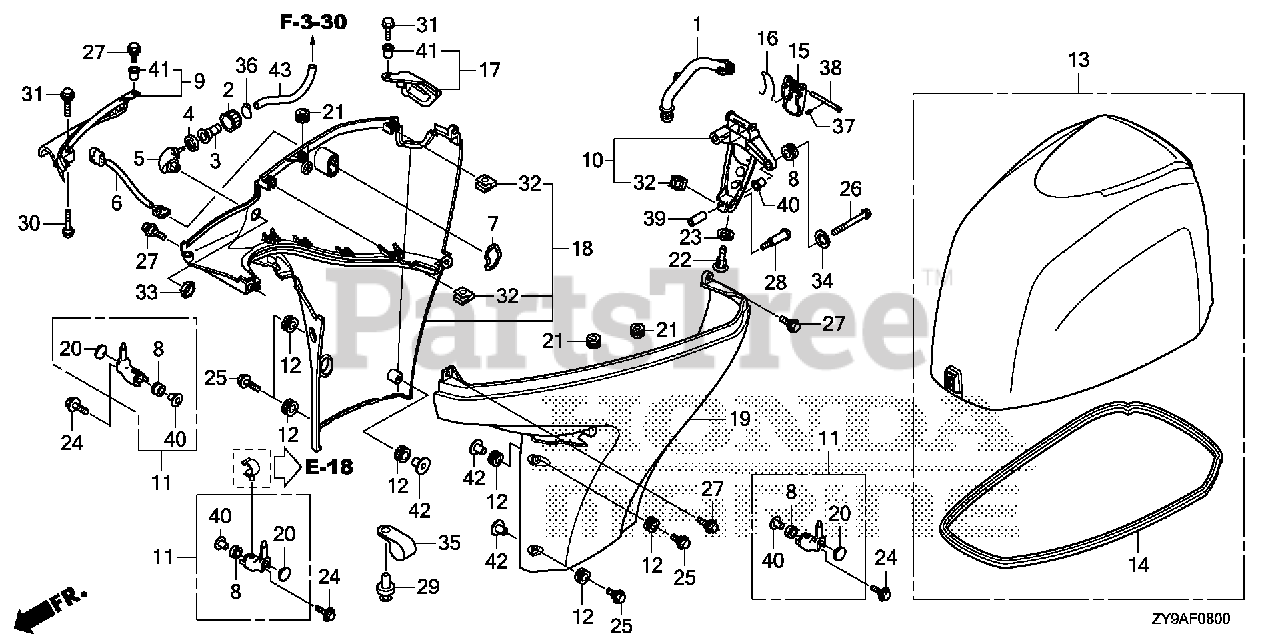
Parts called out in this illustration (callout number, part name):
1	PORT, IDLE EX.
2	NUT, WATER MOUTH
3	JOINT, WATER HOSE
4	SEAT, WATER MOUTH
5	CAP, WATER JOINT
6	SWITCH ASSY., POWER TILT
7	STAY, POWER TILT SWITCH
8	GROMMET, CASE (LOWER)
9	COVER, FR. SEPARATE *NHB14M* (AQUA MARINE SILVER METALLIC)
10	BRACKET, COVER (LOWER)
11	STOPPER ASSY., ENGINE SIDE
12	RUBBER, FENDER MOUNTING
13	COVER ASSY., ENGINE *NHB14M* (AQUA MARINE SILVER METALLIC)
14	SEAL, ENGINE COVER
15	LEVER, FASTENER
16	WIRE, FASTENER
17	COVER, PLUG MAINTENANCE *NHB14M* (AQUA MARINE SILVER METALLIC)
18	COVER, R. ENGINE (LOWER) *NHB14M* (AQUA MARINE SILVER METALLIC)
19	COVER, L. ENGINE (LOWER) *NHB14M* (AQUA MARINE SILVER METALLIC)
20	RUBBER, SEAT SIDE
21	GROMMET, ENGINE COVER
22	GROMMET, WATER CHECK
23	SEAL, WATER CHECK GROMMET
24	BOLT-WASHER (6X27) (CT200)
25	BOLT-WASHER (6X22)
26	BOLT, FLANGE (6X55)
27	BOLT, SPECIAL (6X17)
28	BOLT, RR. BRACKET
29	SCREW, RIVET (5X10)
30	BOLT, SPECIAL (6X37)
31	BOLT, FLANGE (6X20)
33	NUT, HEX. (16MM)
34	WASHER, PLAIN (6MM)
35	CLIP (10.7MM)
36	CLIP B1, TUBE
37	PIN, SPRING (2.0X12)
38	PIN (5X59)
39	COLLAR, DISTANCE (6.5X11X27)
40	COLLAR, MODULE IGNITION CONTROL CASE (CDI)
41	COLLAR, DISTANCE (6.5X9X11.5)
42	COLLAR, DISTANCE (6.2X7.5)
43	BULK HOSE, FUEL (8X1000) (8X300)
